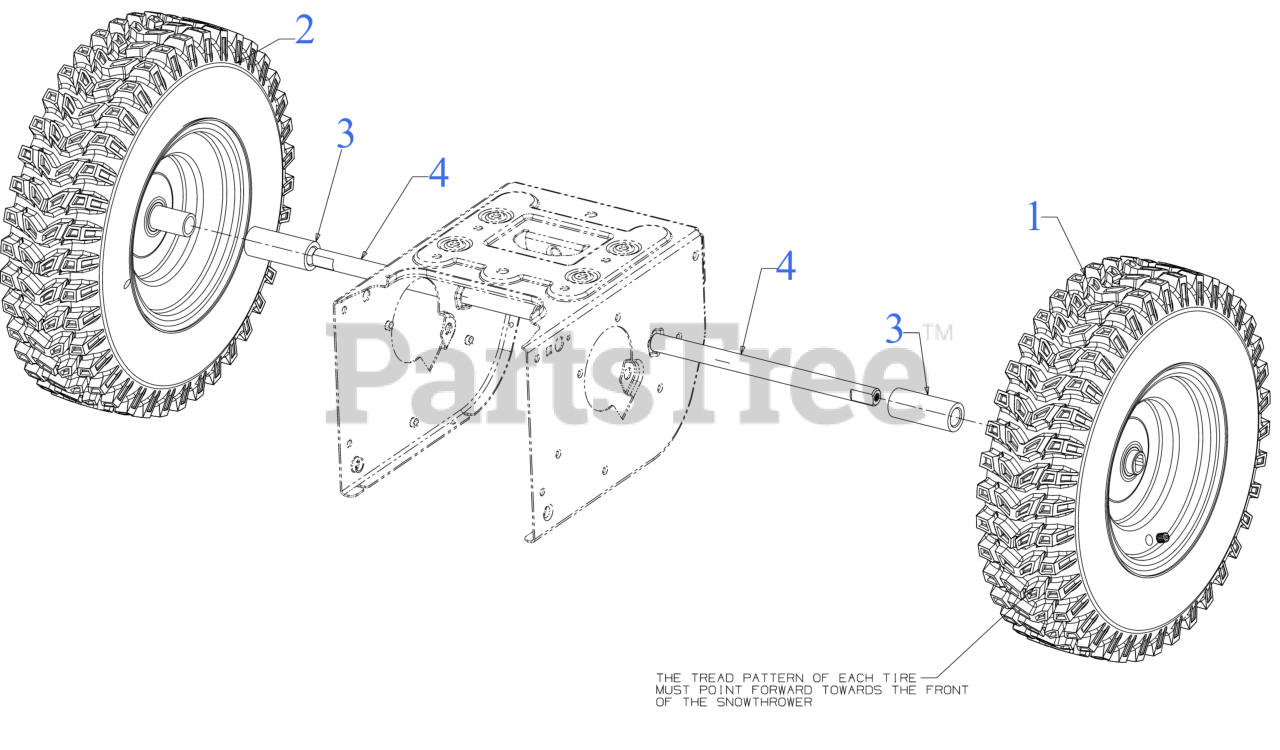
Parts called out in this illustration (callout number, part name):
1	WHL:COMPL:16X4.80-8 X-TRAC:LH
1	TUBELESS AIR VALVE
1	TIRE:X-TRAC:16X4.80-8
2	WHL:COMPL:16X4.80-8 X-TRAC:RH
2	TUBELESS AIR VALVE
2	TIRE:X-TRAC:16X4.80-8
3	WHEEL SPACER 1.25ODX.75X3.00
